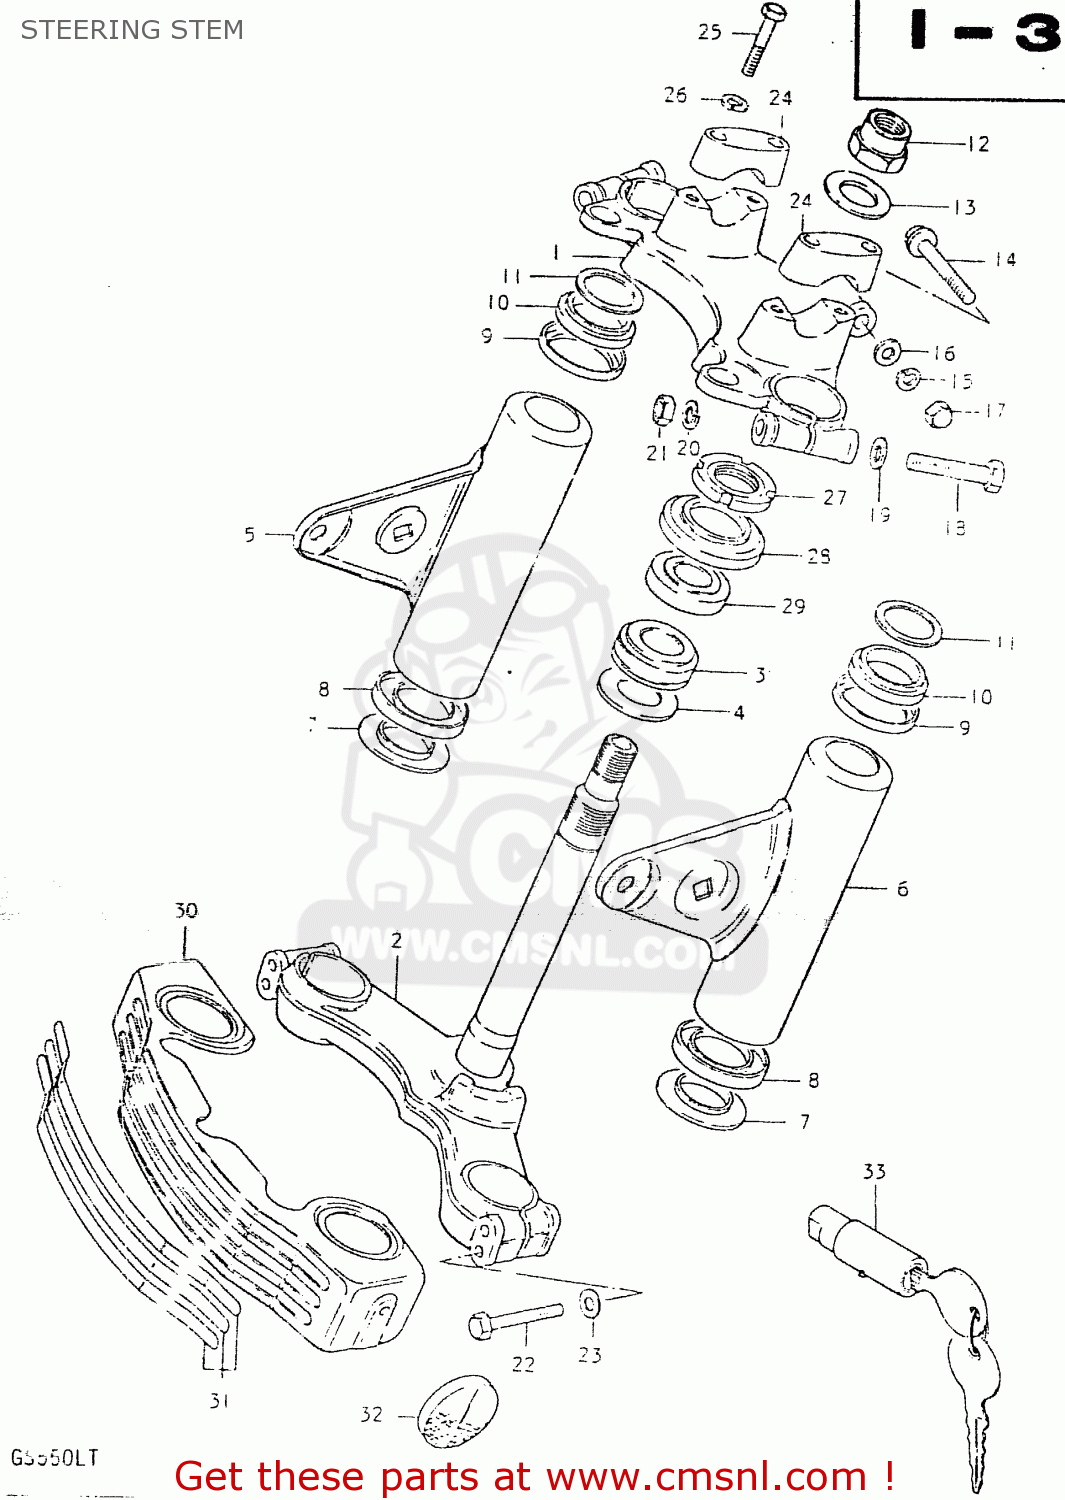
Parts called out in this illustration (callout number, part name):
1	HEAD,STEERING STEM
2	STEM,STEERING
3	BEARING
4	WASHER,THRUST
5	BRACKET,HEADLAMP,RIGHT
6	BRACKET,HEADLAMP,LEFT
7	GUIDE
8	CUSHION,HEADLAMP BRACKET
9	GUIDE
10	CUSHION,HEADLAMP BRACKET UPR
11	SEAT
12	NUT,FR FORK UPR BRACKET
13	WASHER
14	BOLT
15	LOCK WASHER
16	WASHER
17	NUT,M8X1.25X12
18	BOLT 10X55
19	WASHER 5MM
20	LOCK WASHER
21	NUT 10MM
22	BOLT 8X45
23	WASHER,LOCK,8.
24	HOLDER,HANDLE UPR
25	BOLT
26	LOCK WASHER
27	NUT,STEERING STEM(25X44X10)
28	DUST SEAL,STEERING,UPPER
29	TAPER,ROLLER BEARING
30	COVER,FRONT FORK
31	TAPE SET,FRONT FORK COVER
32	REFLEX REFLECTOR,RR
33	LOCK ASSEMBLY,STEERING (NEI
